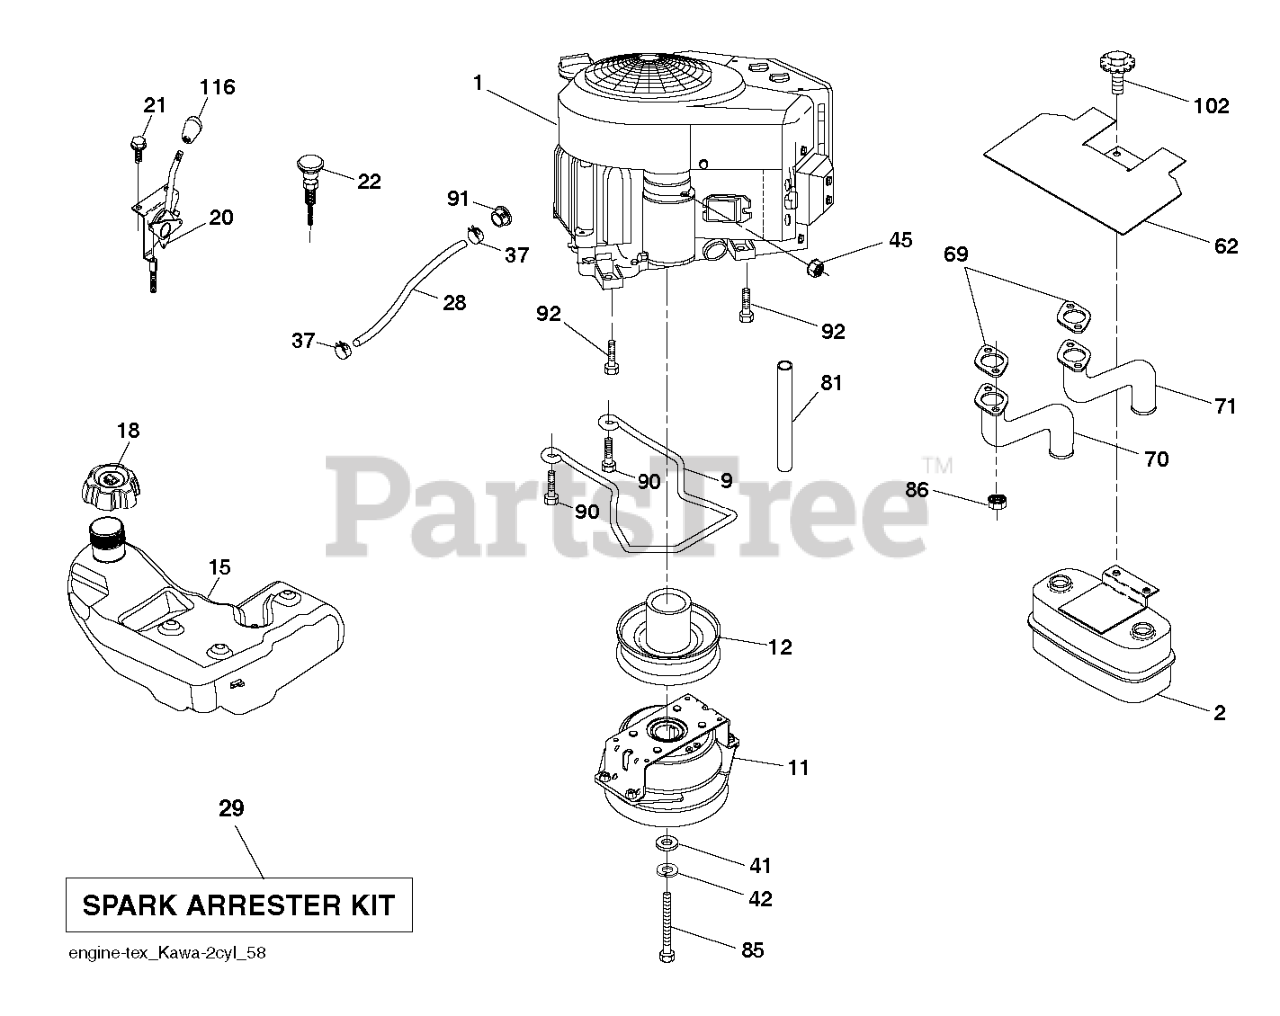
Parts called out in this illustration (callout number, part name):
2	MUFFLER.ASM.TWIN.MNTG.BRACKET
9	KEEPER.BELT.ENG.4.25"2.BLT.431
11	CLUTCH.OGURA.4.4PD.GT1.5-EH13V
12	PULLEY.ENGINE.TUFFTORQ
15	TANK.ASM.3GAL.EPA.17
18	CAP ASSY FUEL 3" GRAY
18	FUEL CAP
20	CONTROL.THROTTLE.PRO.
21	SCREW.#10 X 0.750.BOS
22	CONTROL.CHOKE.ERGO.PUSH-IN.BLA
28	LINE.FUEL.64"REAR.EMIS
29	KIT.SPARK ARRESTOR 794945 B&S
37	HOSE CLAMP
42	LOCKWASHER
45	NUT
62	SHIELD.HEAT.MUFFLER
70	TUBE.EXHAUST.RH.FR961/FR730
71	TUBE.EXHAUST.LH.FR961/FR730
81	TUBE, DRAIN OIL ASM.
85	CLUTCH BOLT7/16-20X3.5 GR524HR
86	NUT.HEX.FLANGE.TOPLOCK
90	SCREW 3/8-16X1
91	BUSHING.1.375OD
92	SCREW 3/8-16X1
102	SCREW
116	KNOB - SHIFT
